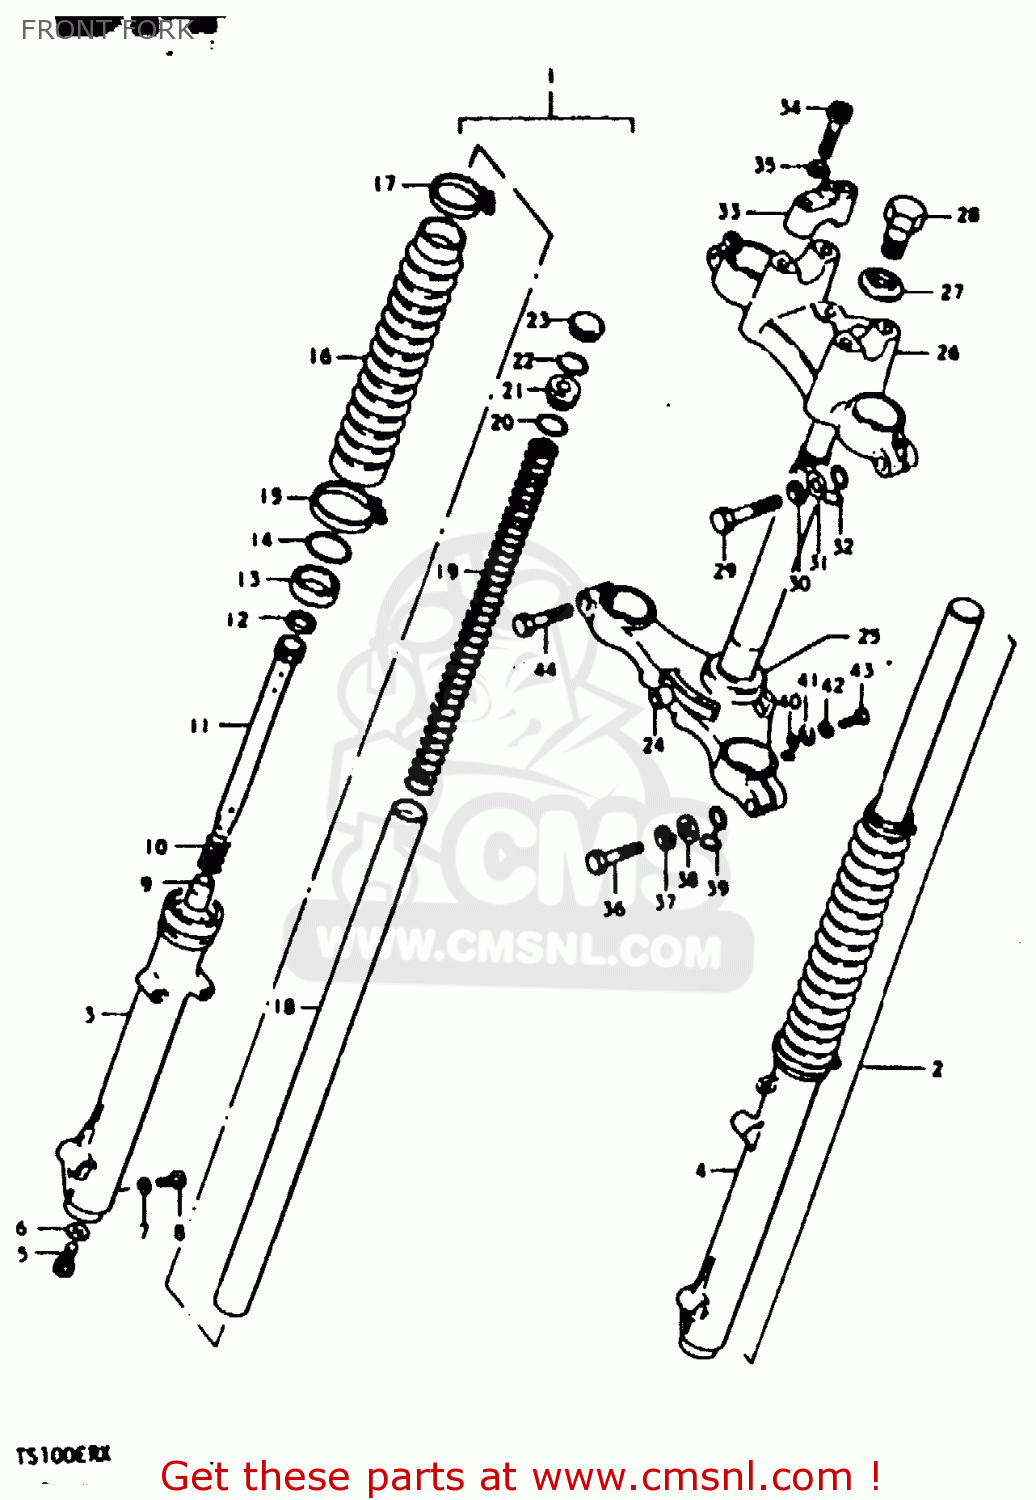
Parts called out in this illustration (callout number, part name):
1	DAMPER ASSEMBLY,RIGHT
2	DAMPER ASSEMBLY,LEFT
3	TUBE,FORK,OUTER,RIGHT
4	TUBE,FORK,LEFT,OUTER
5	BOLT(8X27)
6	GASKET (NAS)
7	GASKET,DRAIN,PLUG (NAS)
8	BOLT(6X8)
9	PIECE,OIL LOCK
10	SPRING,FORK REBOUND
11	CYLINDER,FRONT FORK
12	RING
13	OIL SEAL,FRONT FORK
14	CIRCLIP,FORK OIL SEAL
15	CLAMP
16	BOOT
17	BAND,FRONT FORK COVER BOOT
18	TUBE,FORK,INNER
19	SPRING,FRONT FORK
20	O RING
21	SEAT,SPRING
22	RING,STOPPER
23	CAP,FRONT FORK
24	STEM,STEERING
25	RACE,STEERING OUTER LWR
26	HEAD,STEERING STEM
27	WASHER(10.5X30X2.3)
28	BOLT
29	BOLT
30	LOCK WASHER
31	WASHER
32	CLIP
33	HOLDER,HANDLEBAR
34	BOLT 8X35
35	LOCK WASHER
36	BOLT
37	WASHER,LOCK 12
38	WASHER
39	CLIP
40	CLIP
41	WASHER
42	LOCK WASHER
43	SCREW 6X12
44	BOLT
